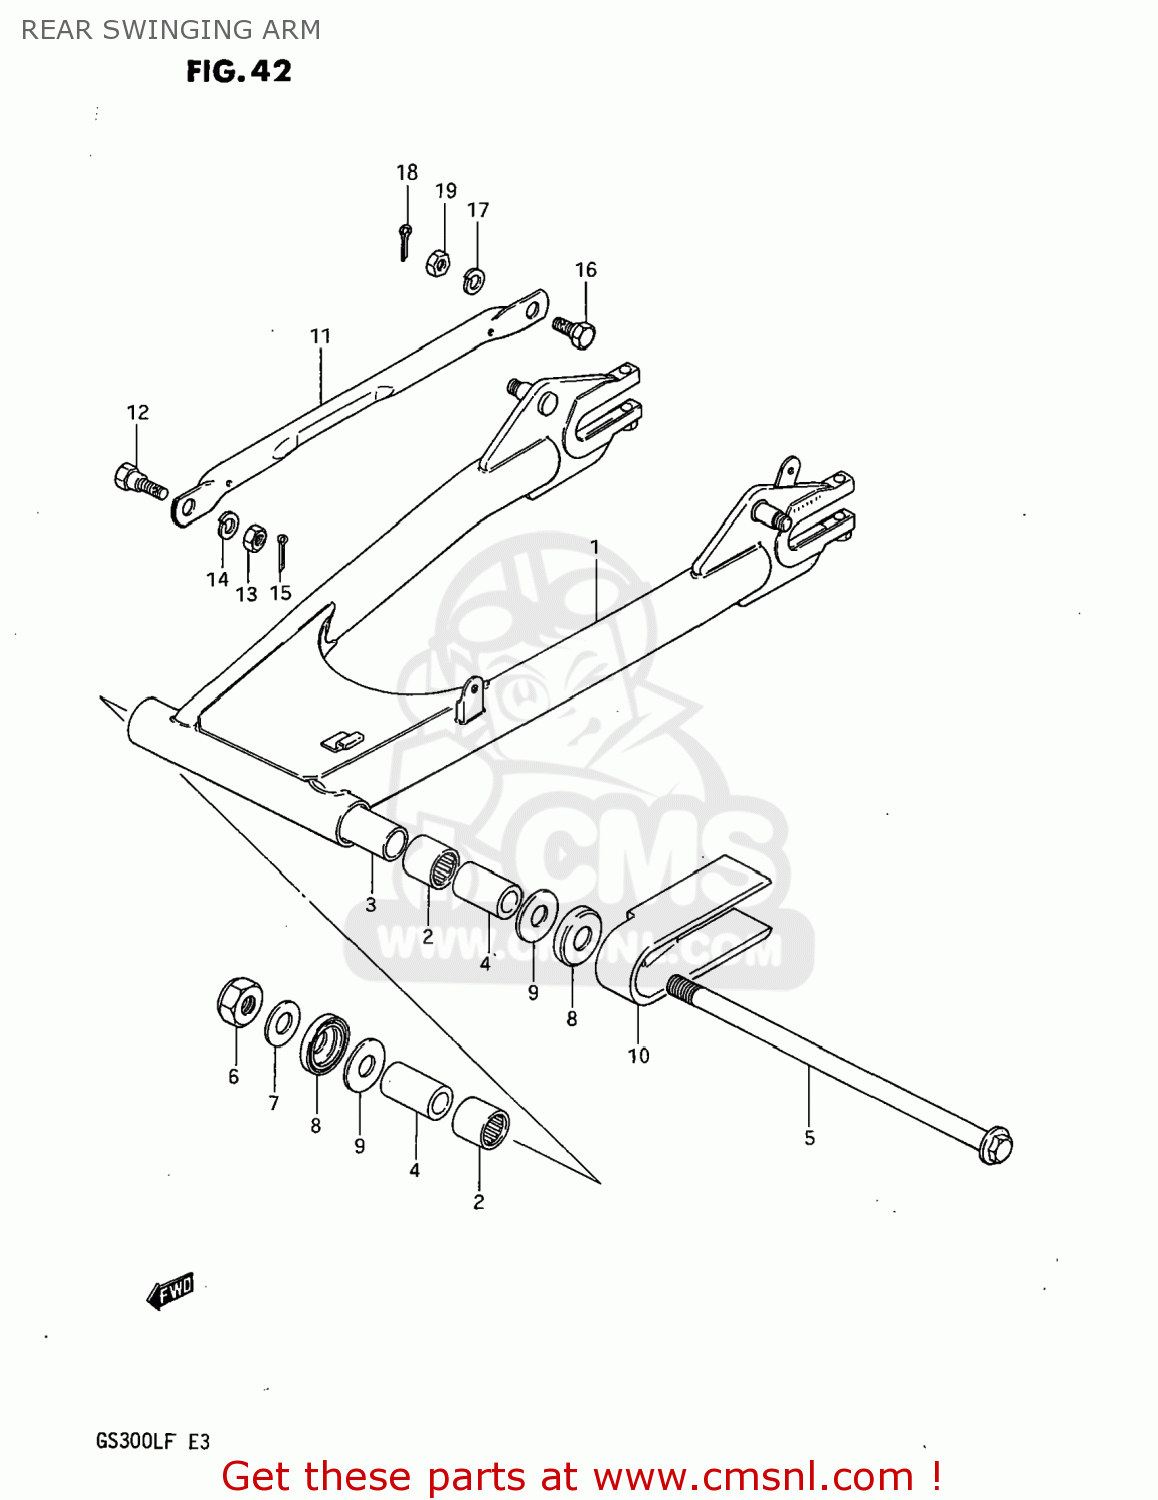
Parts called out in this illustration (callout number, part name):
1	ARM,REAR SWING
2	BEARING(22X29X30)
3	SPACER,SWINGINGARM CTR
4	SPACER,RR SWGARM PIVOT
5	SHAFT,REAR SWING ARM
6	NUT 14MM
7	WASHER
8	CVR,RR SWGARM DUST SEAL(OD:40)
9	WASHER(14.2X34X1)
10	BUFFER,CHAIN TOUCH DEFLECTOR
11	LINK,REAR TORQUE
12	BOLT(10X24.5)
13	NUT
14	LOCK WASHER
15	PIN 20X20
16	BOLT(10X31)
17	LOCK WASHER
18	PIN 20X20
19	NUT
